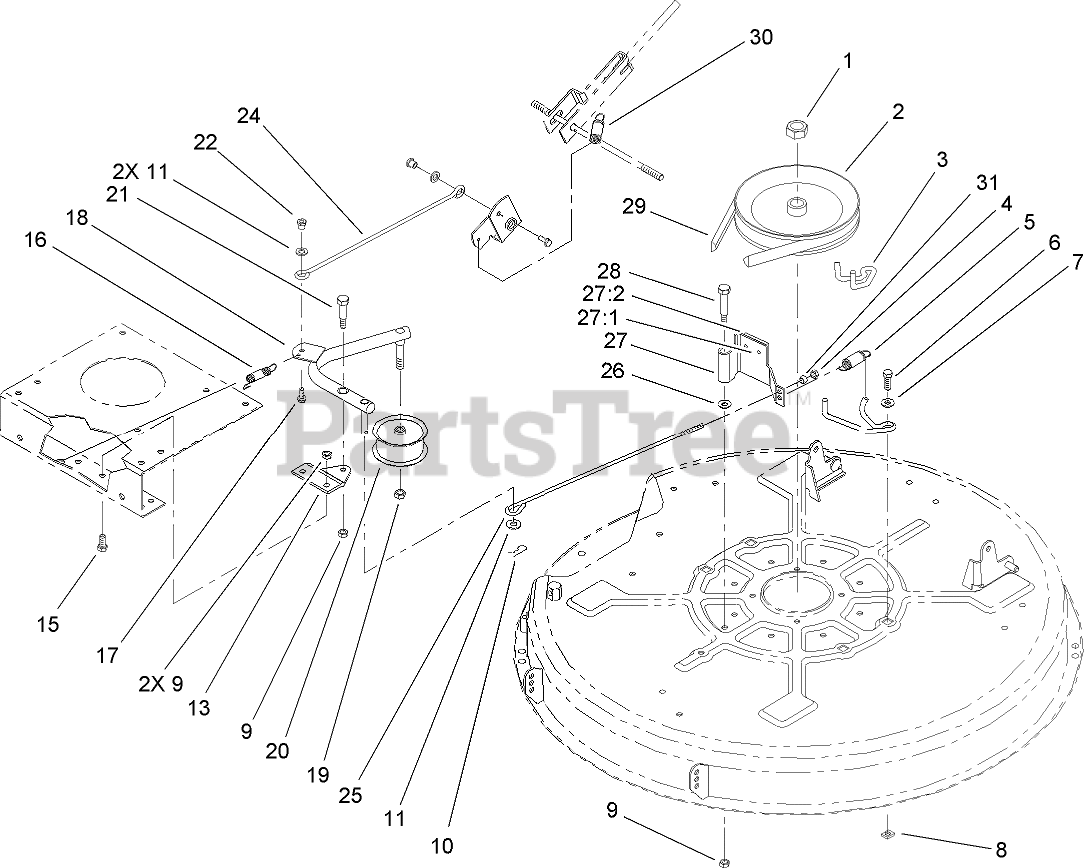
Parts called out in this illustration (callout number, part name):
1	NUT-HEX
2	PULLEY-DECK
3	GUIDE-BELT, DECK
4	NUT-LOCK, NI
5	SPRING-EXTENSION
6	SCREW-HH
7	WASHER-PIVOT
8	NUT-RETAINER
9	NUT-LOCK, NI
10	PIN-COTTER
11	WASHER-FLAT
13	PLATE-MOUNTING, IDLER
15	SCREW-HH
16	SPRING-RETURN, BRAKE
17	SCREW-HHF
18	ARM-IDLER WA (BLACK)
19	NUT-LOCK, NI
20	PULLEY-IDLER
21	SCREW-SHOULDER, HH
22	POST-MOUNTING, LINKAGE
24	ROD-ENGAGE, DECK
25	ROD-BRAKE, DECK
26	WASHER-PLAIN
27	BRAKE ARM ASM
27:1	RIVET-BLIND
27:2	PAD-BRAKE
28	BOLT-SHOULDER
29	V-BELT
30	CABLE SPRING ASM
31	BALL-SWIVEL, STOP
